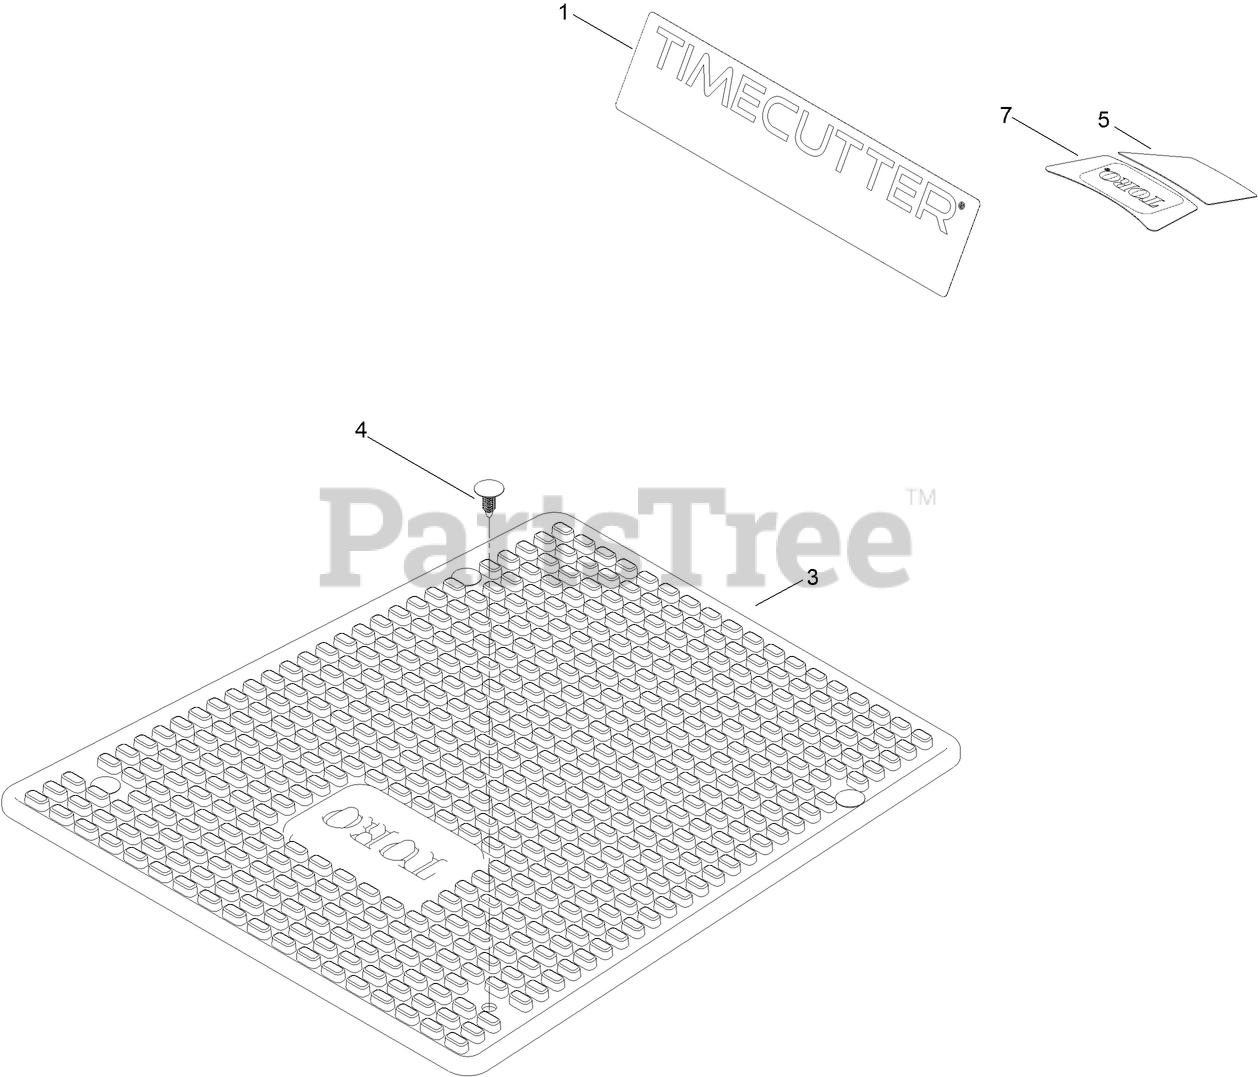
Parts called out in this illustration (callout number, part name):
1	DECAL-TIMECUTTER
3	MAT-FLOOR
4	PLUG-PLASTIC
5	DECAL-DISPLACEMENT, ENGINE
7	DECAL-ENGINE
